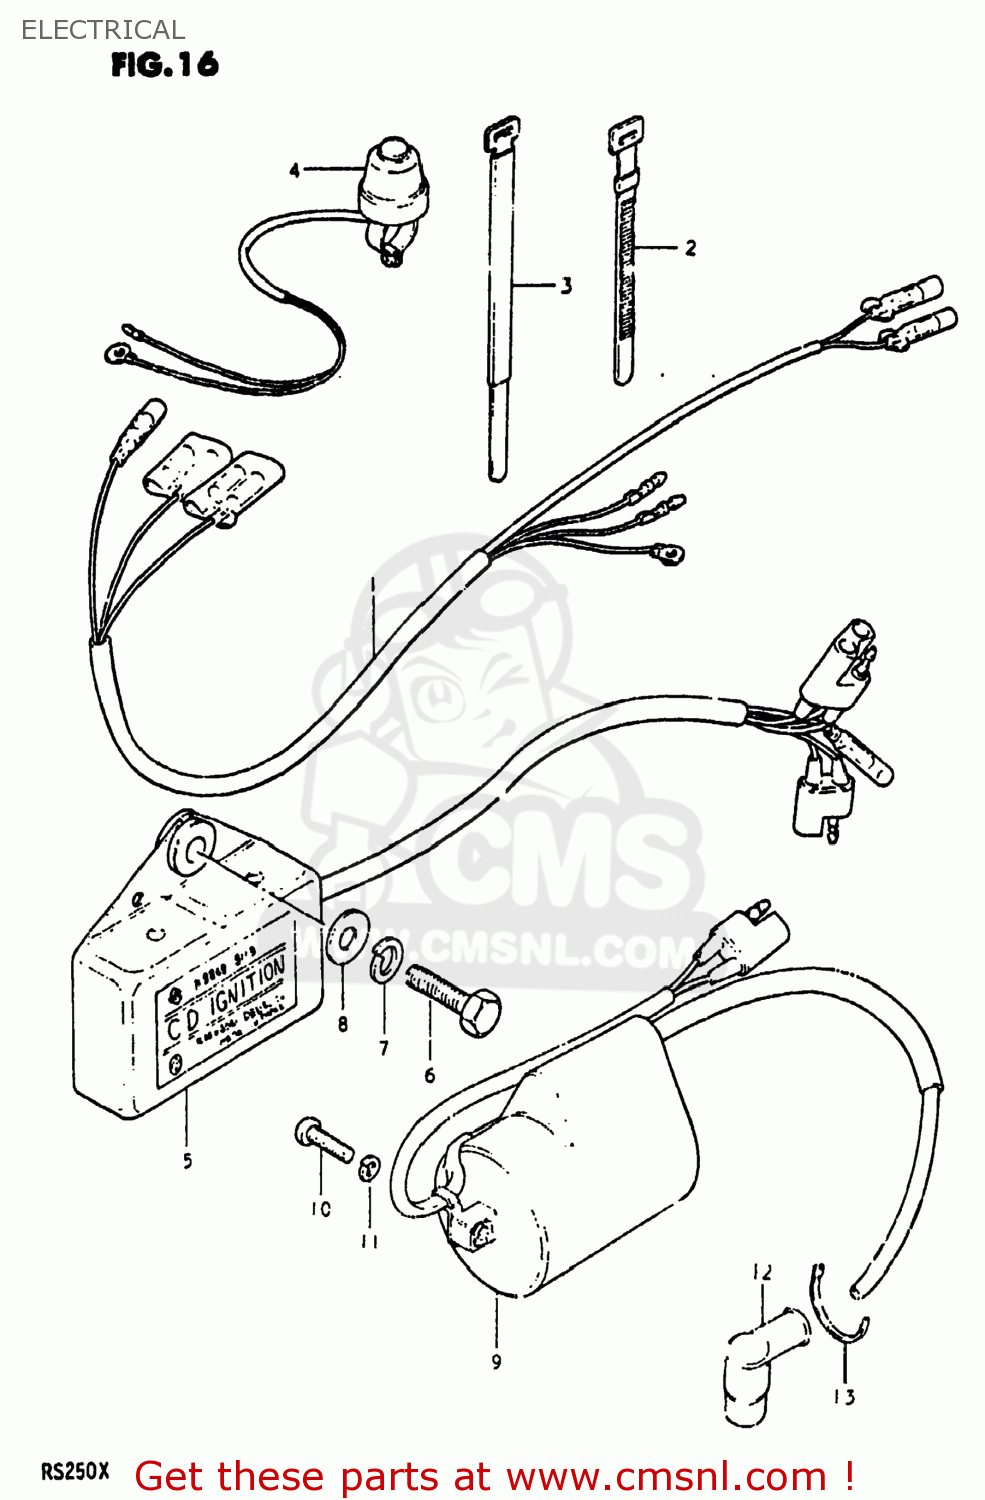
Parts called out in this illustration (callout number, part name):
1	HARNESS,WIRING
2	CLAMP(L:120)
3	CLAMP
4	SWITCH ASSEMBLY
5	CDI UNIT ASSEMBLY
6	BOLT
7	LOCK WASHER
8	WASHER(6.5X16X1.2)
9	COIL ASSEMBLY,IGNITION
10	SCREW 5X20
11	LOCK WASHER
12	CAP,SPARK PLUG
13	CLAMP
